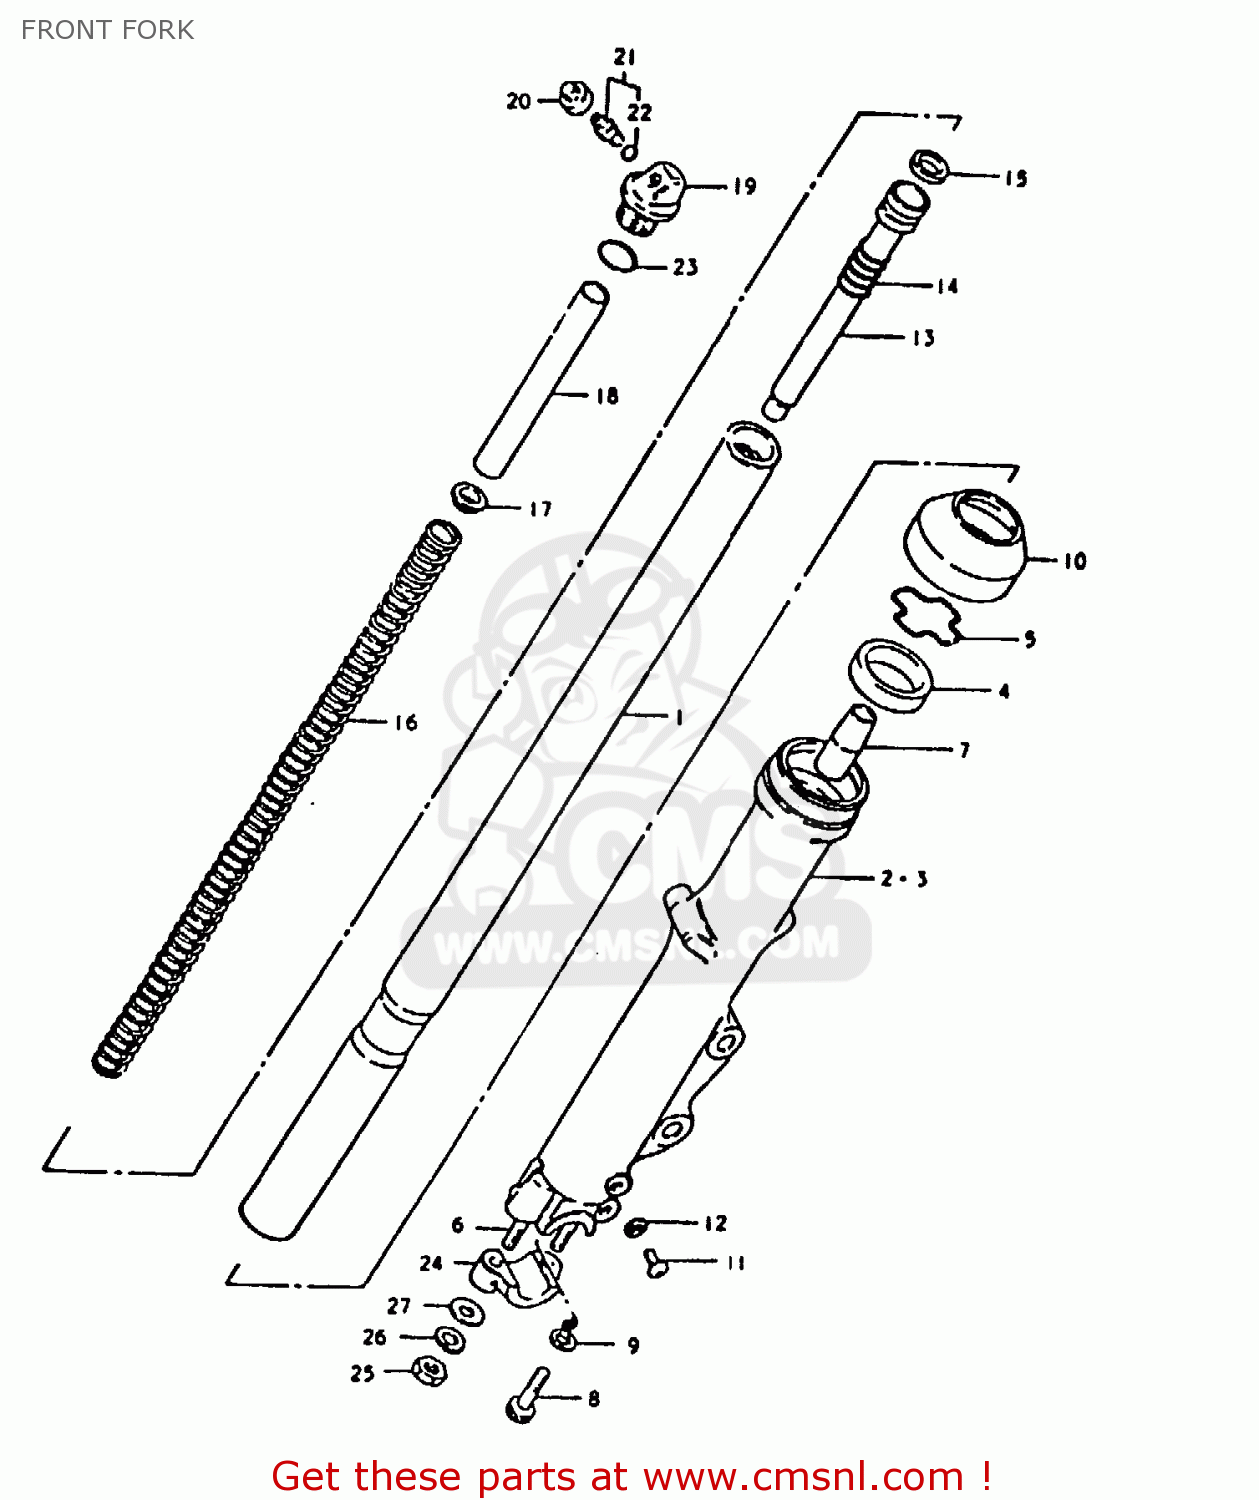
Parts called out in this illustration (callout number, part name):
1	TUBE,FORK,INNER
2	TUBE,FORK,OUTER,RIGHT
3	TUBE,OUTER,LEFT
4	OIL SEAL,FRONT FORK
5	RING,STOPPER
6	STUD BOLT
7	PIECE,OIL LOCK
8	BOLT,FORK CYLINDER(10X25)
9	GASKET (NAS)
10	SEAL,DUST
11	SCREW
12	GASKET,DRAIN,PLUG (NAS)
13	CYLINDER,FRONT FORK
14	SPRING,REBOUND
15	RING,PISTON
16	SPRING,MAIN
17	GUIDE,FRONT FORK SPRING C
18	SPACER,FRONT FORK SPRING
19	CAP
20	CAP,VALVE
21	VALVE
22	O RING
23	O RING
24	HOLDER,AXLE
25	NUT (8MM)
26	LOCK WASHER
27	WASHER
